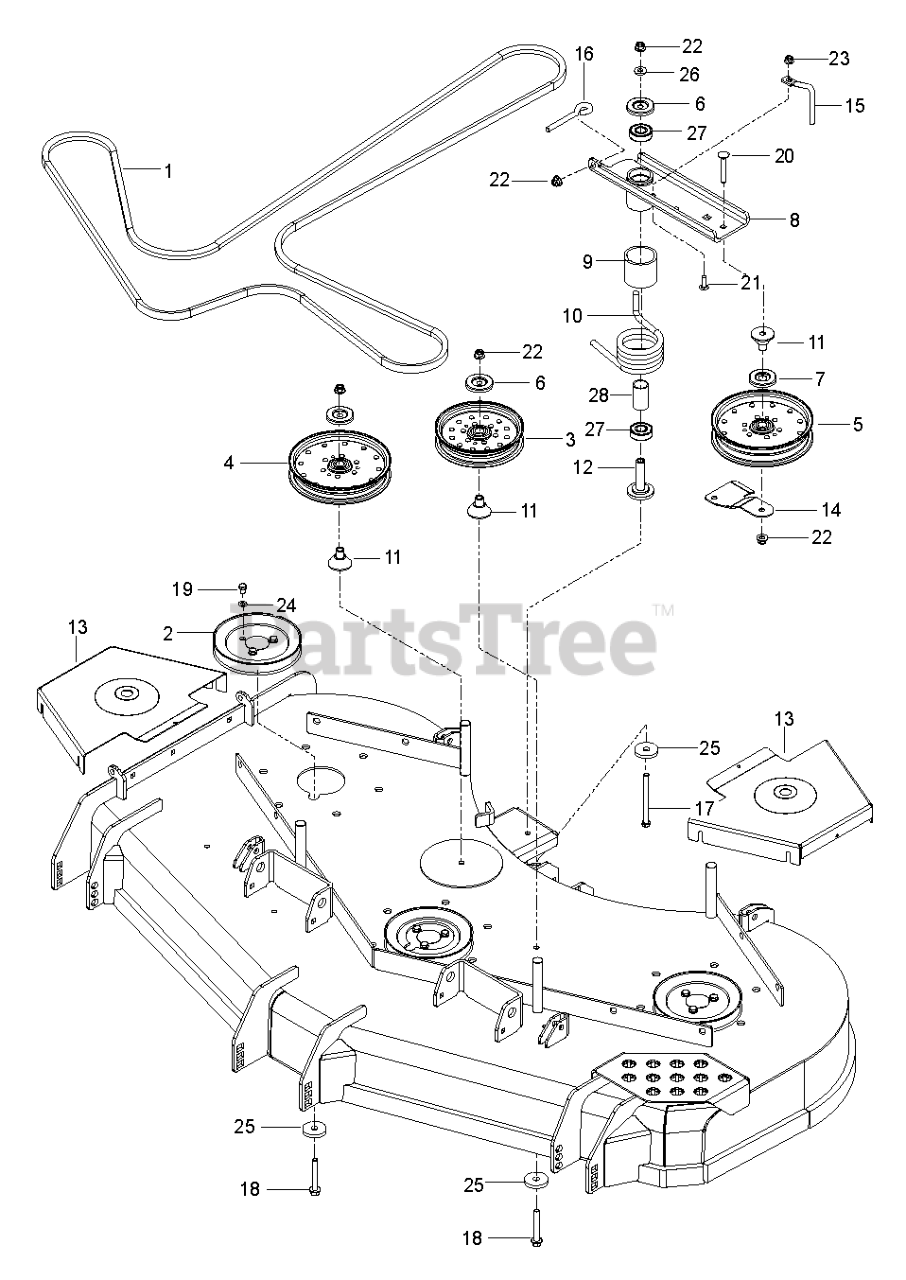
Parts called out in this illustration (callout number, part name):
1	BELT 5V 176.00
2	PULLEY - 7.50
3	PULLEY - 7" NARROW
4	PULLEY IDLER, 6" NARROW
5	PULLEY - IDLER 7"
6	DUST SHIELD
7	SHIELD, DUST
8	IDLER.ARM.BLACK
9	SPACER, IDLER PIVOT
10	SPRING, TORSION, IDLER
11	BEARING, IDLER ARM
12	BEARING, IDLER PIVOT
13	SHIELD BELT 72 L.H. X672 SNAPP
14	BELT.GUIDE.BLACK
15	BELT KEEPER
16	EYE BOLT, 3/8 X 4"
17	HCS 3/8-16 X 4-1/2 GR 8 ZD
18	HHFS 3/8-16 X 2-3/4 GR5 ZD
19	HCS 5/16-18 X 1/2 GR 5 ZD
20	CARRIAGE BOLT 3/8-16 X
21	RHSSNB 5/16C X 1.0
22	NUT 3/8-16 HEX FLG NYLOC ZD
23	5/16-18 NYLOC FLANGE NUT
24	WASH 5/16 DISC SPRING ZD
25	SPINDLE WASHER
26	WASHER, 3/8 THICK
28	SPACER, IDLER BEARINGS
